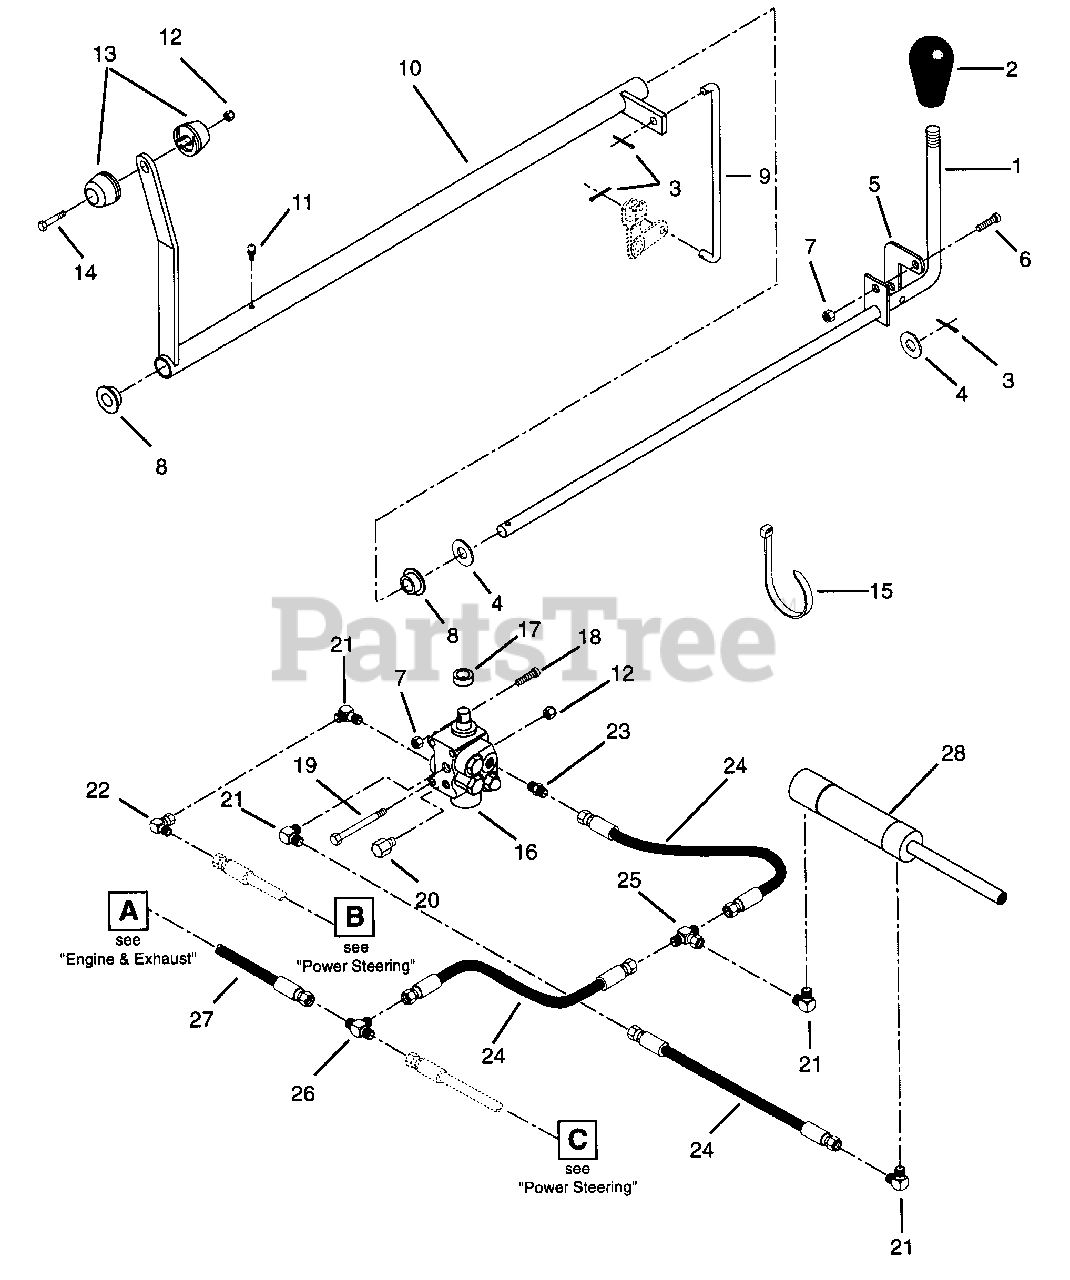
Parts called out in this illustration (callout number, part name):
1	Weldment,Lift Lever
2	Knob,PTO
3	Pin-Cotter .09 x .75
4	Washer-Flat-Steel .531 x 1.000 x .063
5	Rod,Hydraulic Control
6	Screw-Machine 10-24 x .625
7	Nut-Locking 10-24
8	Bushing-Flange .515 x .750 x .745 x 1.00
9	Rod,Hi-Lo Control
10	Lever,Hi-Lo Control Weldment
11	Fitting-Lube .25-28 x .256
12	Nut-Locking-Nylon .250-20 Grade 2
13	Knob,Control
14	Bolt-Hex .25-20 x 1.50 Grade 5
15	TieWrap, Black
16	Valve,Hydraulic
17	Spacer .700 x 1.00 x .31
18	Screw-Machine 10-24 x 1.00
19	Bolt-Hex .25-20 x 2.75
20	Plug .44-20
21	Adapter
22	Adapter
23	Adapter-Pipe .56-18
24	Assembly,Hydraulic Hose
25	Adapter,Fitting Tee
26	Adapter-Tee .56-18
27	Assembly,Hydraulic Hose
28	Cylinder,Lift
